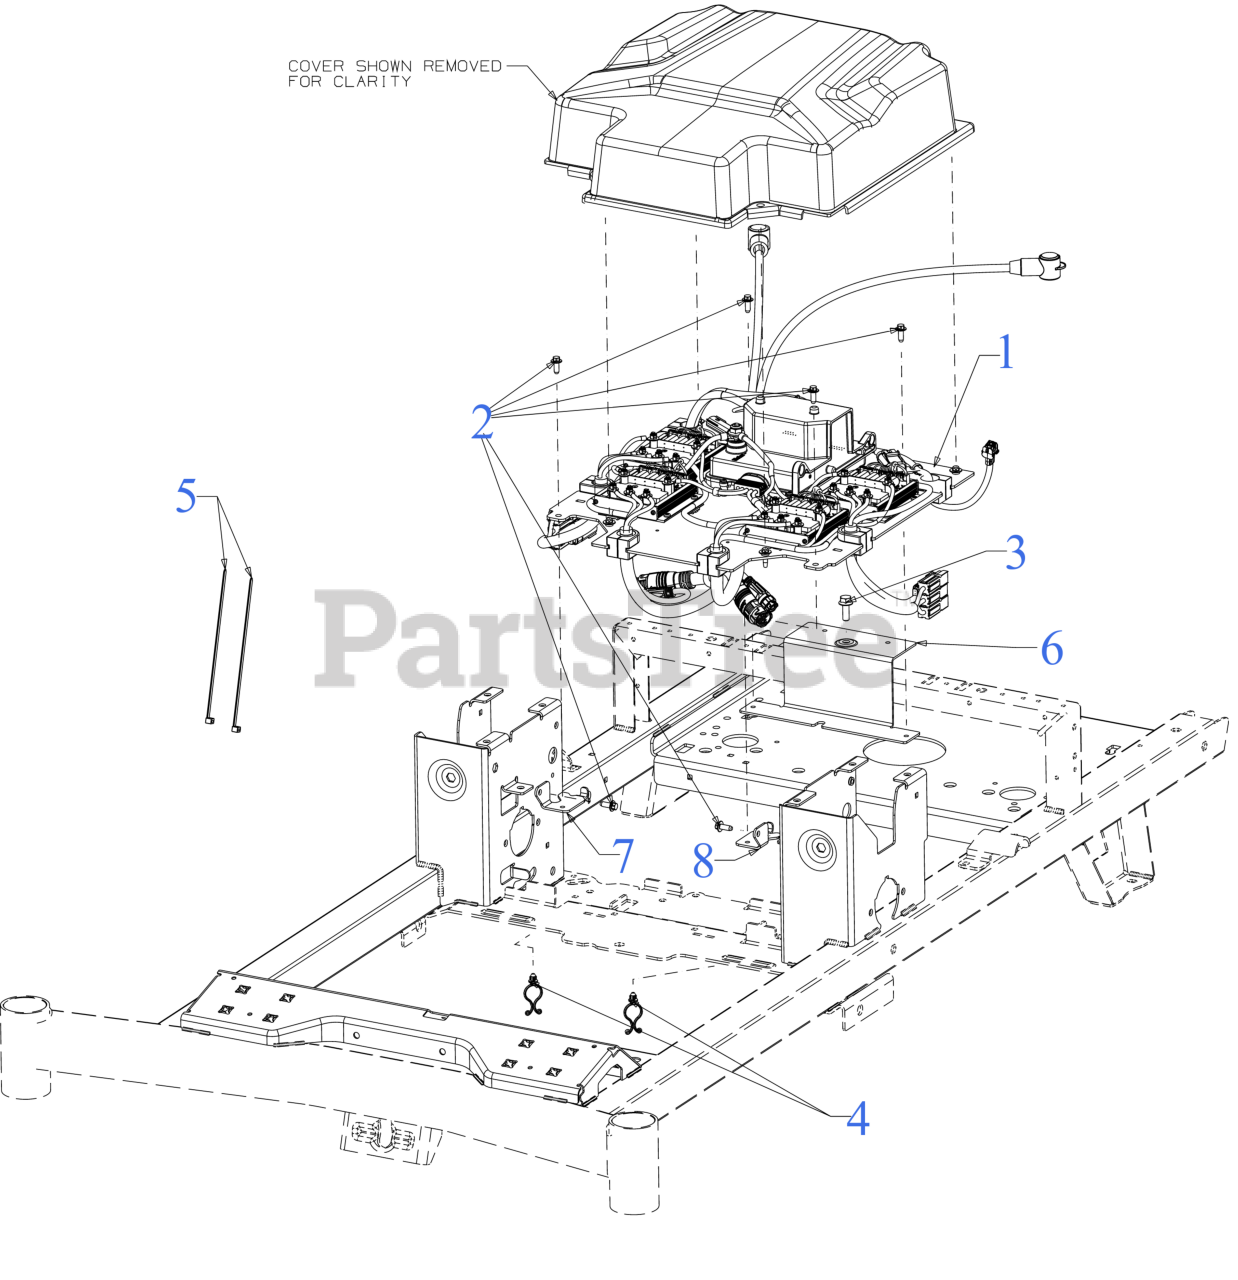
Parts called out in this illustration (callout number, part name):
1	Not Serviceable/ Components Only
2	SCREW M6-1 x .625
3	SCREW 5/16-18 x .875 GR5 HXFLG HD
4	TWIST LOCK CLIP
5	7" CABLE TIE
6	PANEL BRACKET (REAR)
7	PANEL BRACKET (RH)
8	PANEL BRACKET (LH)
